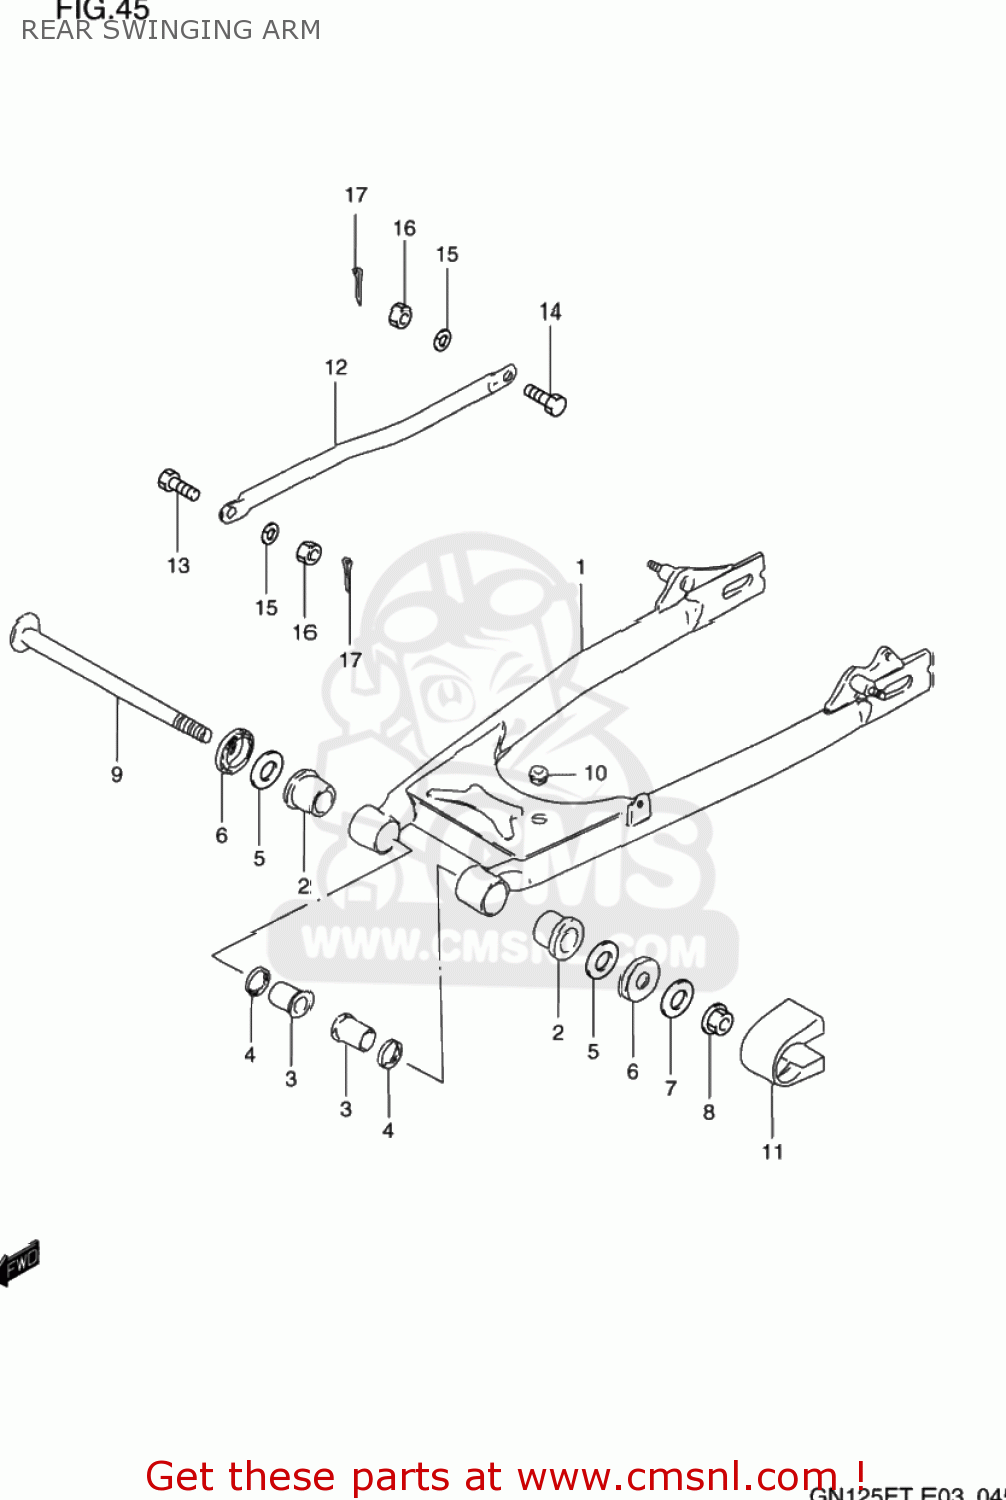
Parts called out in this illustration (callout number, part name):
1	SWINGINGARM ASSY,RR
2	BUSH,RR SWINGING ARM PIVOT
3	SPACER,RR SWGARM PIVOT
4	SEAL,OIL(20X27X5)
5	WASHER
6	CVR,RR SWGARM DUST SEAL(OD:40)
7	WASHER
8	NUT 14MM
9	SHAFT,REAR SWING ARM
10	CUSHION
11	BUFFER,CHAIN TOUCH DEFENSE
12	LINK,RR TORQUE
13	BOLT(8X22.5)
14	BOLT(8X26.5)
15	LOCK WASHER
16	NUT
17	PIN 20X20
